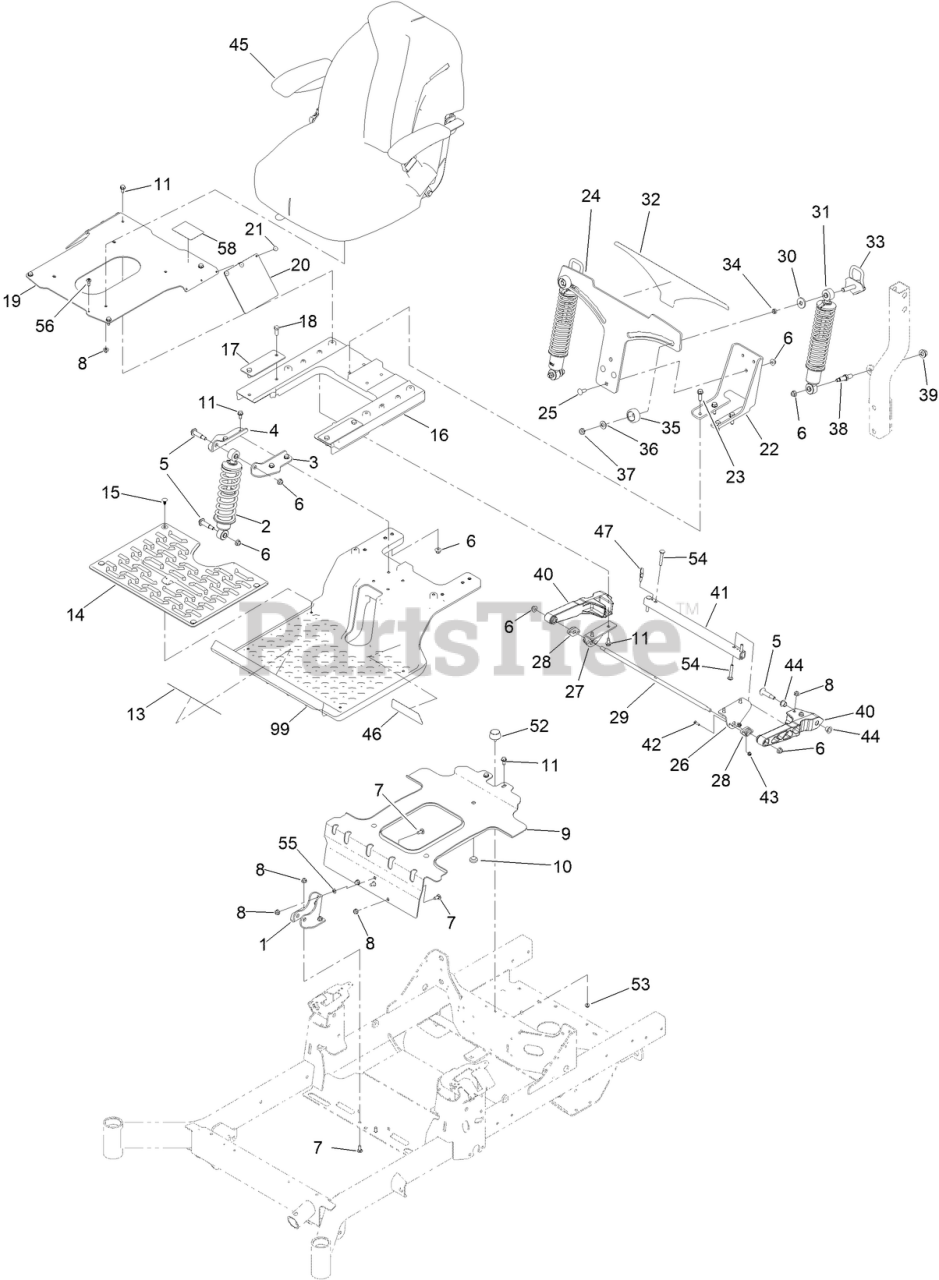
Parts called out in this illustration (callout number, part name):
1	BRACKET-SHOCK, FRONT LOWER
2	SHOCK/SPRING
3	BRACKET-SHOCK MOUNT, UPPER (LH)
4	BRACKET-SHOCK MOUNT, UPPER (RH)
5	BOLT-SHOULDER, HWH
6	NUT-HF, NI
7	SCREW-CARR
8	NUT-HF, NI
9	BRACKET-TANK
10	BUMPER-SEAT
11	SCREW-HWHTF
13	DECAL-DANGER
14	FLOOR MAT
15	PLUG-PLASTIC
16	SUBFRAME-REAR
17	PLATE-BACKER
18	SCREW-HH
19	PLATE-SEAT
20	FLAP-RUBBER
21	RIVET-POP
22	BRACKET-MOUNT, LOWER
23	SCREW-THD
24	PLATE-MOUNTING, ADJ SHOCK
25	SCREW-CARR
26	BRACKET-ARM, TRAILING (LH)
27	BRACKET-ARM, TRAILING (RH)
28	BEARING-FLANGE
29	ROD-PIVOT
30	WASHER-PLASTIC
31	SHOCK/SPRING ASM
32	DECAL-MYRIDE
33	CAM LOCK ASM
34	BEARING-SLEEVE
35	KNOB-LOCK, CAM
36	WASHER-ADJUSTING
37	NUT-HEX
38	BOLT-SHOULDER
39	NUT-LOCK
40	TRAILING ARM
41	TUBE-ARM, TRAILING
42	SCREW-CARR
43	NUT-HF
44	BUSHING-FLANGE
45	SEAT-FIXED TORO
47	CLAMP-HOSE
52	BUMPER
53	NUT-HF
54	BOLT-CARR
55	NUT-PUSH
56	SCREW-SHOULDER
58	DECAL-AID, SERVICE
99	SUBFRAME-FRONT
99	SUBFRAME-FRONT RED
